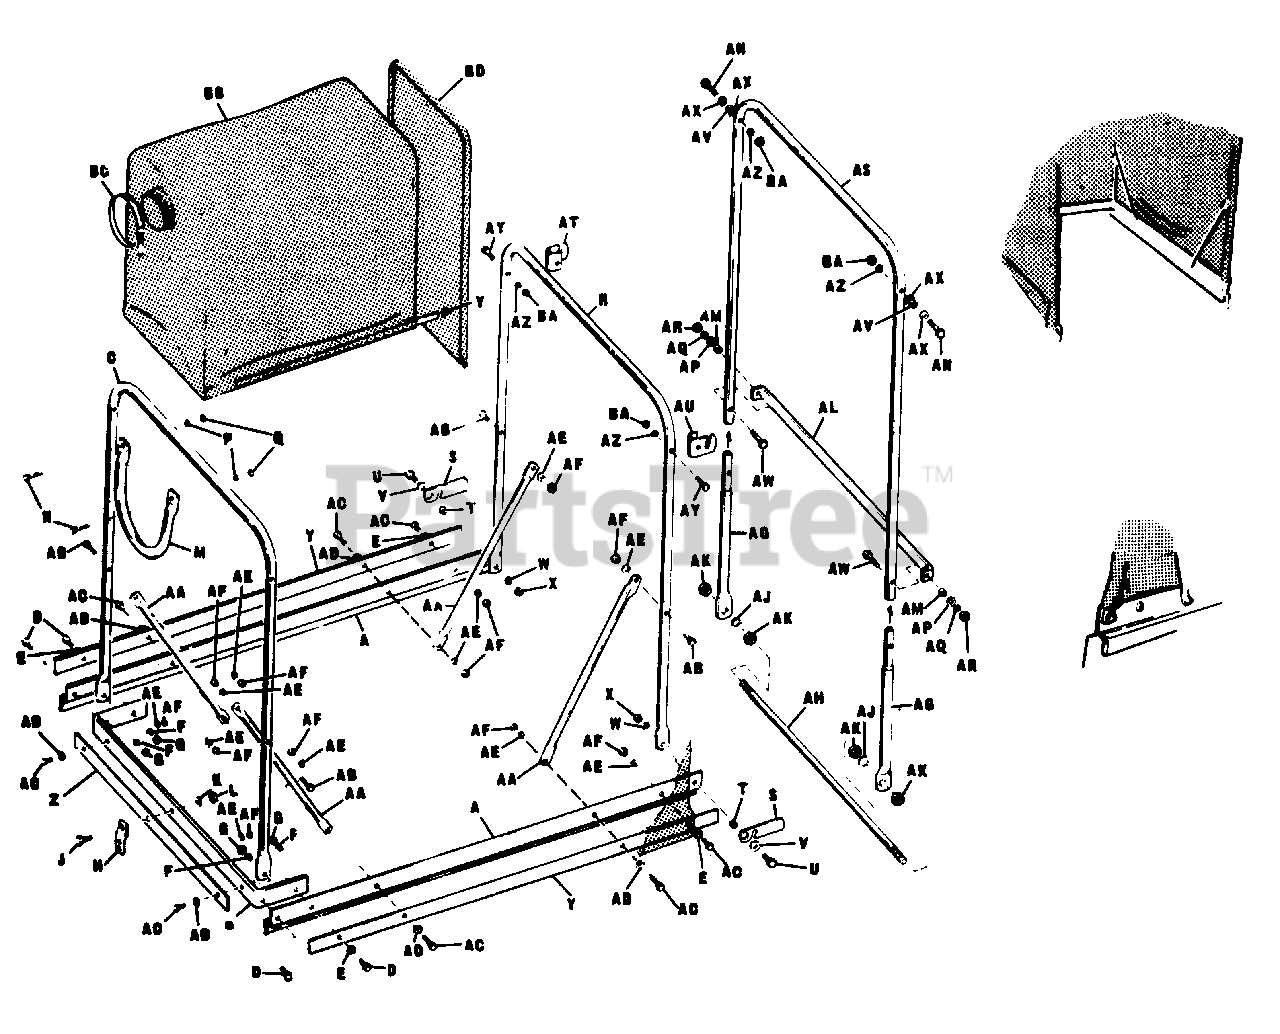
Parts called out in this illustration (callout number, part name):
A	"Z" Bar, Side
B	Front Bar
C	Front and Rear Upright
D	Hex Capscrew, 5/16"-18 x 1" lg.
E	Plain Washer, 5/16"
F	Lock Washer, 5/16"
G	Hex Nut Full, 5/16"-18
J	Hex Capscrew, 3/8"-16 x 1" lg.
K	Plain Washer, 3/8"
L	Hex Lock Nut, Full, 3/8"-16
M	Hose Support
N	Hex Capscrew, 1/4"-20 x 1-1/4 lg.
P	Lock Washer, 1/4"
Q	Hex Nut Full, 1/4"-20
R	Front and Rear Upright
S	Rear Door Latch
U	Hex Capscrew, 5/16"-18 x 7/8" lg.
V	Plain Washer, 5/16"
W	Lock Washer, 5/16"
X	Hex Nut Full, 5/16"-18
Y	Hold Down Strip, Side
Z	Hold Down Strip, Front
AA	Cross Brace Tube
AB	Hex Capscrew, 1/4"-20 x 1-1/4" lg.
AC	Hex Capscrew, 1/4"-20 x 3/4" lg.
AD	Plain Washer, 1/4"
AE	Lock Washer, 1/4"
AF	Hex Nut, Full, 1/4"-20
AG	Tube, Rear Door
AH	Rod Rear Door
AJ	Lock Washer, 1/2"
AK	Hex Nut, Full, 1/2"-13
AL	Bar, Rear Door
AN	Hex Capscrew, 1/4"-20 x 1-3/4" lg.
AP	Plain Washer, 1/4"
AQ	Lock Washer, 1/4"
AR	Hex Nut Full, 1/4"-20
AS	Top Rear Door
AT	Catch, Door. R.H.
AU	Catch, Door. L.H.
AW	Hex Capscrew, 1/4"-20 X 1-3/4" lg.
AX	Plain Washer, 1/4"
AY	Hex Capscrew, 1/4"-20 x 1-1/4" lg.
AZ	Lock Washer, 1/4"
BA	Hex Nut, Full, 1/4"-20
BC	Hose Strap
